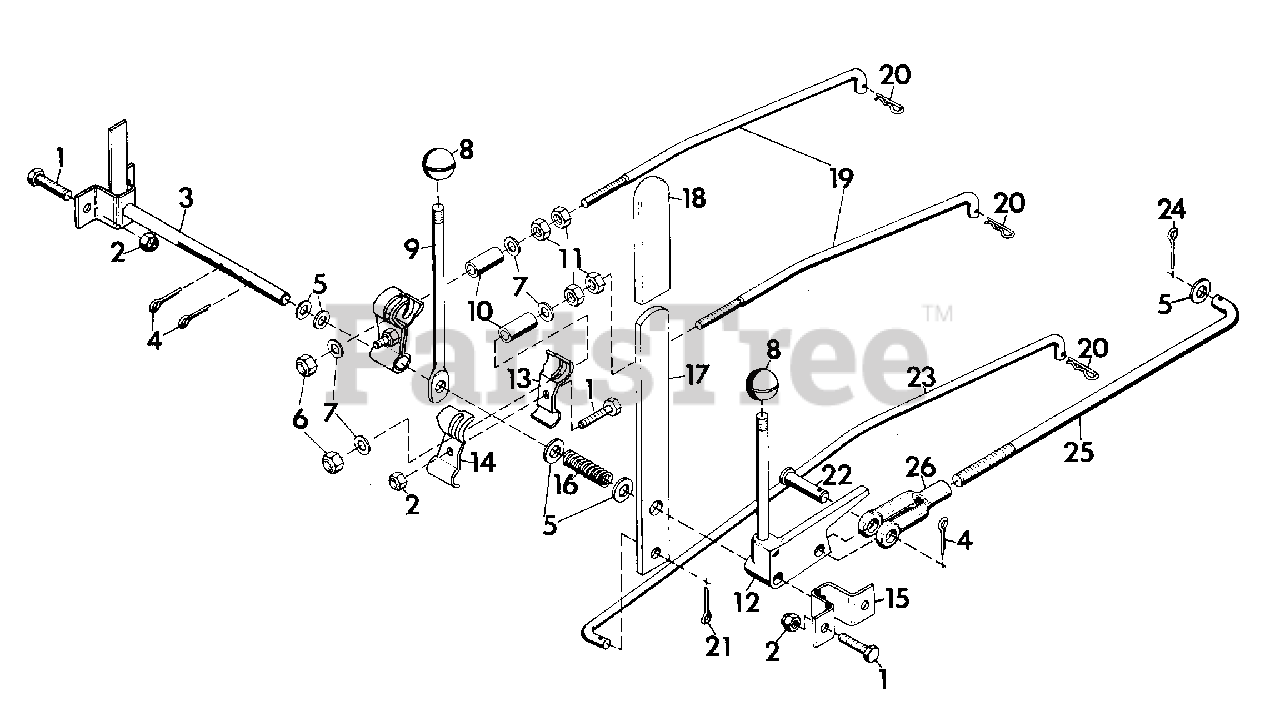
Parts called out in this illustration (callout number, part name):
1	BOLT, HEX 5/16-18X.75
2	NUT, LOCK 5/16-18
3	WELDMENT, CROSS SHAFT
4	PIN, COTTER .12X1.0
5	WASHER, FLAT .531X1.06X.095
6	NUT, LOCK 3/8-16
7	WASHER, FLAT .438X1.00X.083
8	KNOB, CONTROL
9	LEVER, SHIFT
10	BUSHING, .400X.500X1.65
11	NUT, JAM 3/8-16
12	ASSEMBLY, PTO CONTROL
13	ARM, SHIFTER R.H.
14	ARM, SHIFTER L.H.
15	BRACKET, CROSS SHAFT
16	SPRING, COMPRESSION
17	LEVER, HI-LO
18	GRIP, HANDLE
19	ROD, SHIFT
20	COTTER, HAIR PIN
21	PIN, COTTER .09X.75
22	PIN, CLEVIS .500X1.213
23	ROD, 2-SPEED
24	PIN, COTTER .125X1.00
25	ROD, PTO
26	YOKE, 1/2-20 ADJUSTABLE
